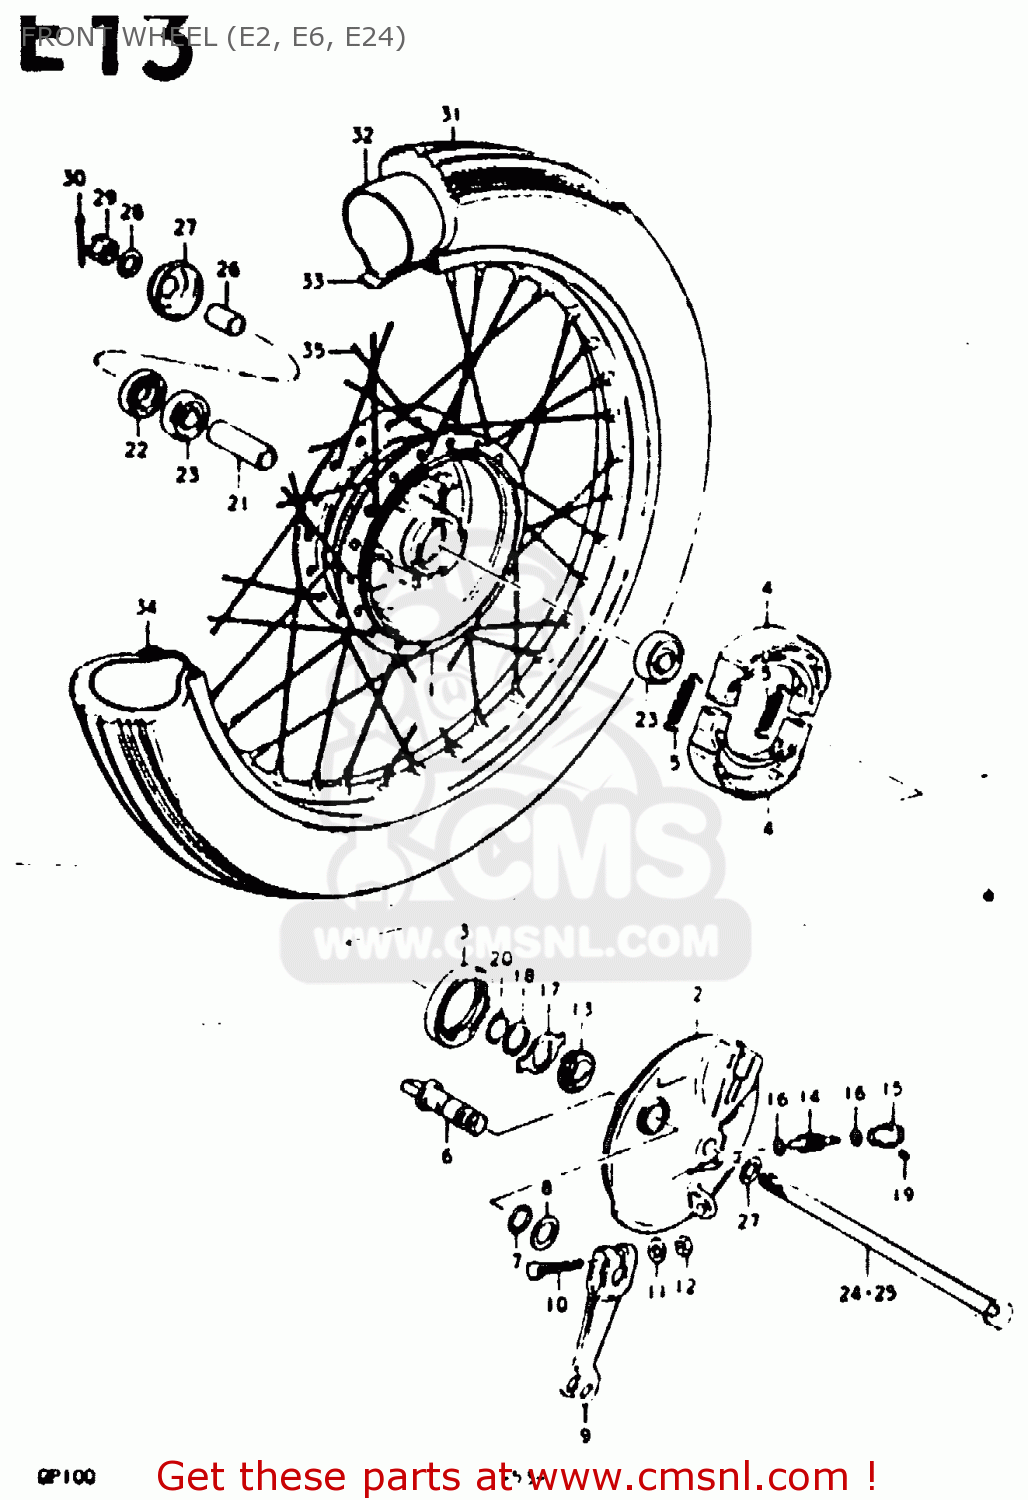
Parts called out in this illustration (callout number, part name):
1	HUB, FRONT
2	PANEL, FRONT HUB
3	SEAL,OIL(48X62X7)
4	SHOE,BRAKE
5	SPRING(L:34)
6	CAM,FRONT BRAKE
7	O-RING (D:2.4 ID:13.8)
8	WASHER (14.5X22X1.6)
9	LEVER,FR BRAKE CAM
10	BOLT(6X35)
11	WASHER
12	NUT
13	GEAR,SPEEDOMETER
14	PINION,SPEEDOMETER
15	BUSH,METER GEAR OUTER
16	WASHER (5.1X9X0.4)
17	DRIVER
18	WASHER(18.5X24X1)
19	SCREW
20	CIRCLIP
21	SPACER(12.6X19X47)
22	OIL SEAL(17X38X5)
23	BEARING
24	AXLE,FRONT
26	SPACER, RH
27	COVER
28	WASHER
29	NUT
30	COTTER PIN
31	TIRE,FRONT
32	TUBE,INNER
33	PROTECTOR,WHEEL,INNER
34	RIM,WHEEL(1.40X18)
35	SPOKE SET
